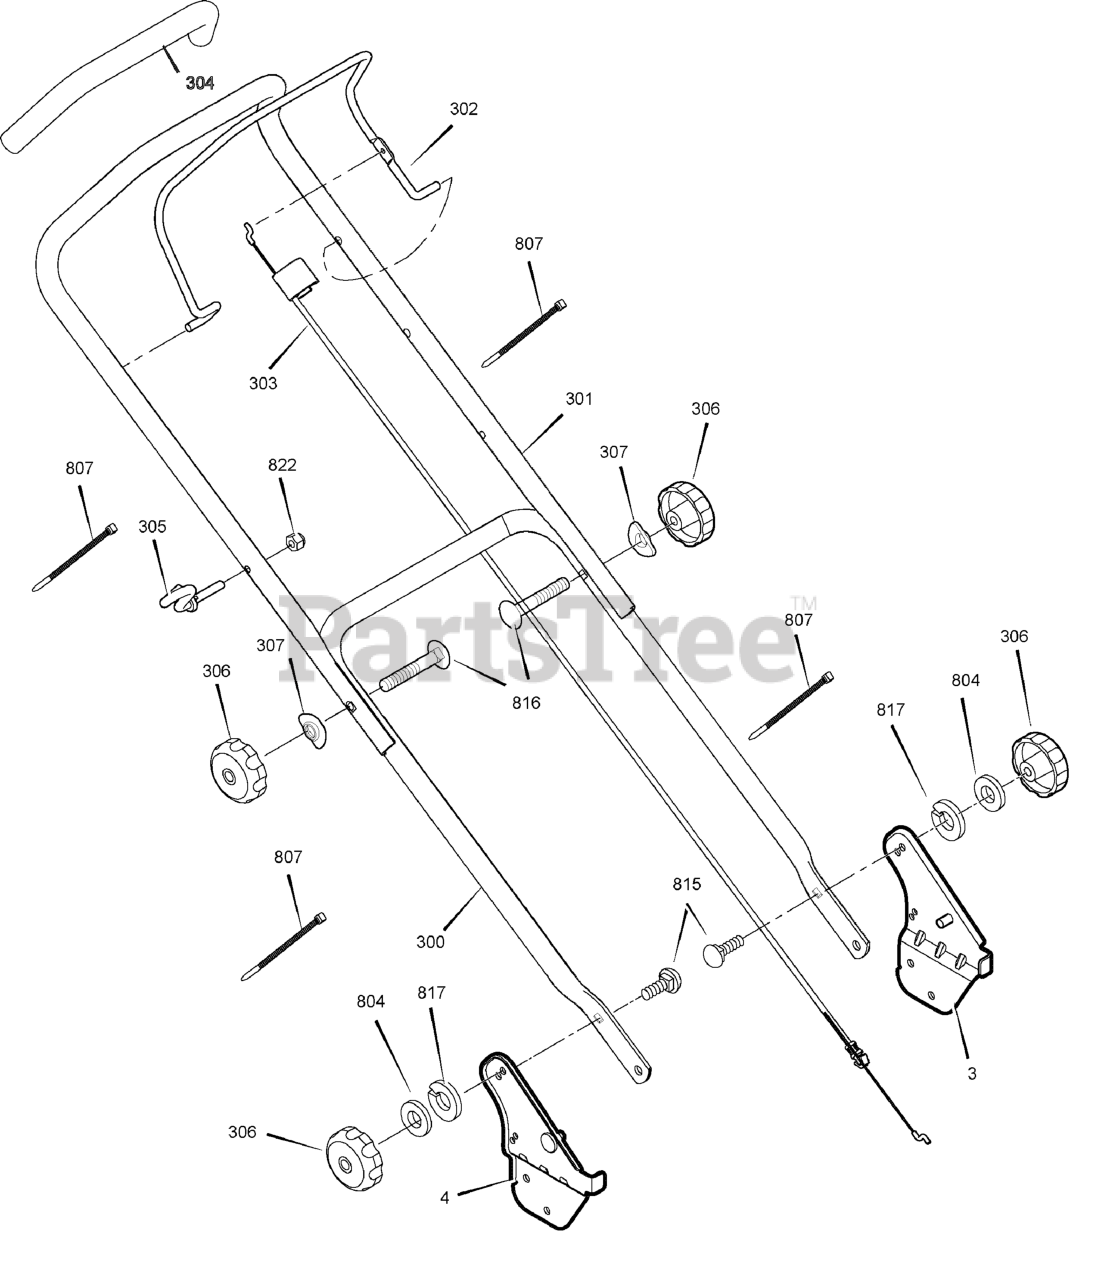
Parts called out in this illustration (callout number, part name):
3	BRACKET ASSEMBLY, Left Handle
4	BRACKET ASSEMBLY, Right Handle
300	HANDLE, Lower
301	HANDLE, Upper
302	LEVER, Engine Stop
303	CABLE, Engine Stop
304	TUBING, Foam
305	GUIDE, Rope
306	KNOB, 5/16-18
307	WASHER, Formed
804	WASHER, 5/8
807	CABLE TIE
815	BOLT, Carriage, 5/16-18 x 1-1/8
816	BOLT, Carriage, 5/16-18 x 2
817	Washer, Lock
822	NUT, Hex, 1/4-20
